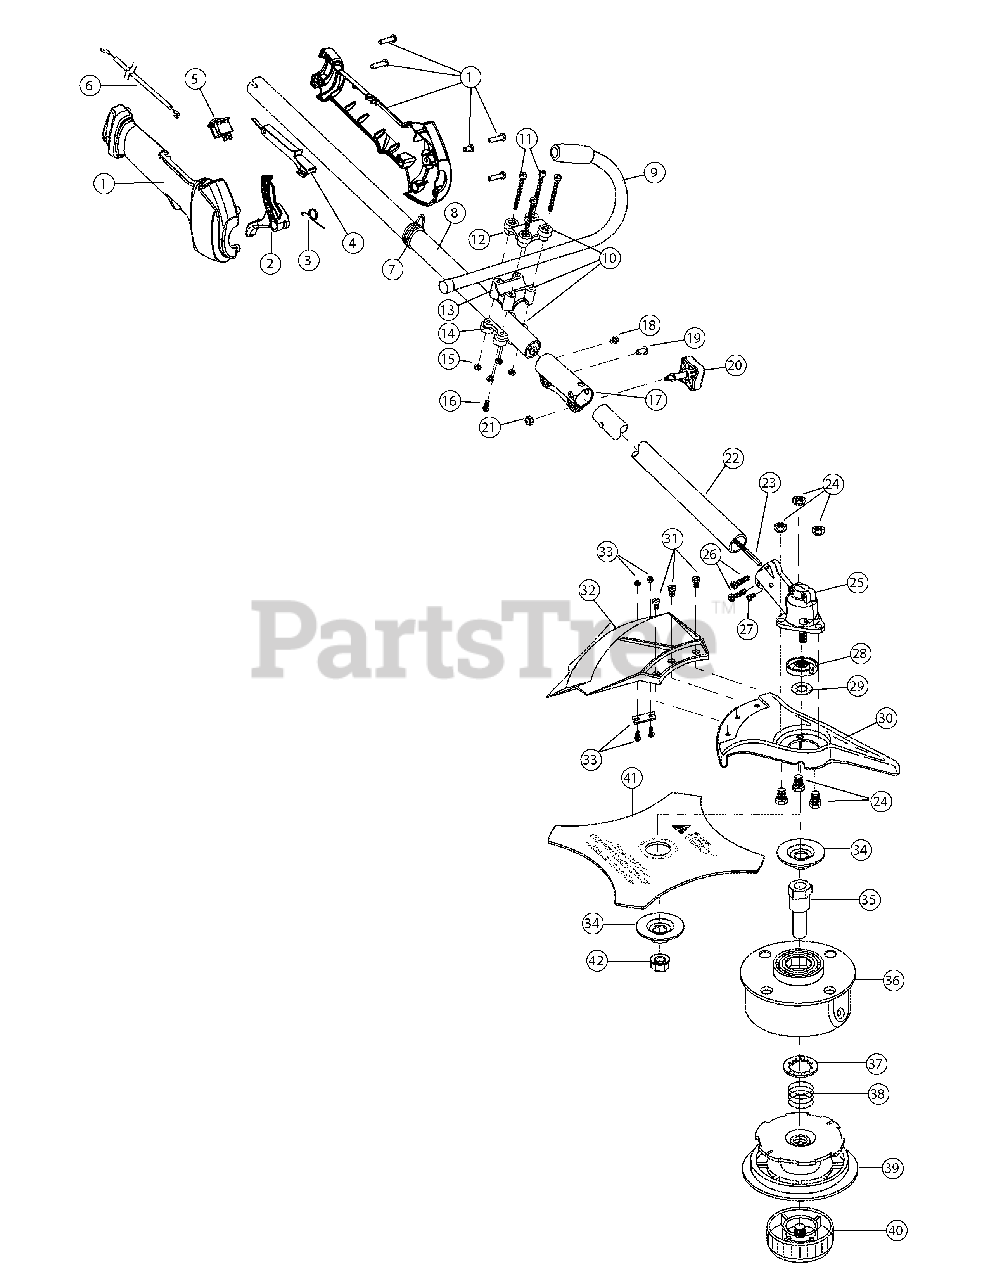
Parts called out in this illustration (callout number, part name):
1	Throttle Housing Assembly
2	Throttle Trigger
3	Throttle Trigger Spring
4	Throttle Trigger Lock-Out
5	Switch Assembly
6	Throttle Cable Assembly
7	Harness Clip
8	Upper Drive Shaft Housing Assembly
9	J-Handle Assembly
10	Handle Bracket Assembly
12	Upper Handle Clamp
13	Middle Handle Clamp
14	Lower Handle Clamp
16	Anti-Rotation Screw
17	Split Boom Coupler
20	Adjustment Knob
21	Knob Retaining Nut
22	Lower Drive Shaft Housing Assembly
23	Lower Flexible Drive Shaft
24	Shield Mount Screw Assembly
25	2 piece Gearbox Assembly
26	Gearbox Mounting Hardware
27	Anti-Rotation Screw
28	Blade Driver
30	Blade Shield/Shield Mount
31	Shield Mounting Screw
32	Shield Assembly
33	Blade Assembly
34	Retaining Washer
35	Spool Shaft
36	Outer Spool Assembly
37	Retainer
40	Bump Head Knob Assembly
41	4-Tooth Blade
42	Nut
